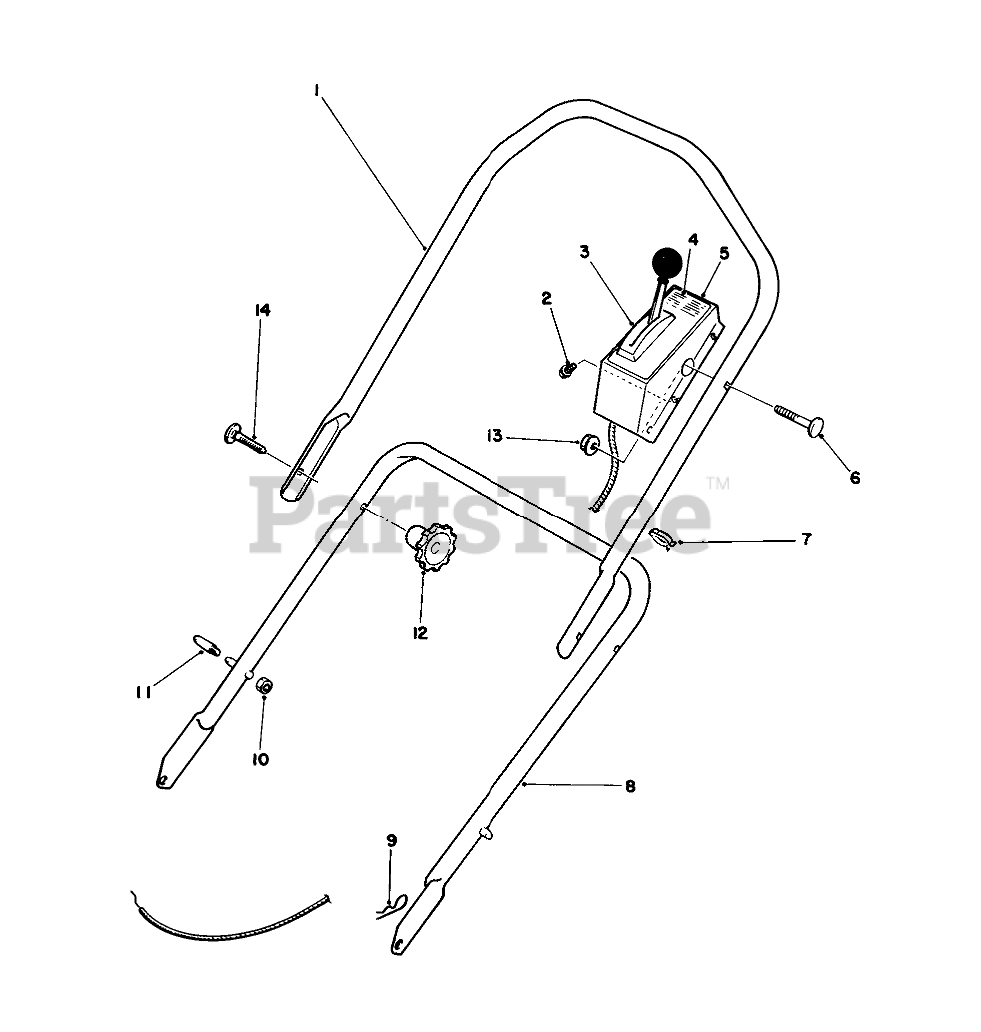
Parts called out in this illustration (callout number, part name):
1	Handle-Upper
2	SCREW-HWHTF
3	THROTTLE CONT-SERVICE
4	CONTROL COVER DECAL
5	Cover-Control (Incl. Ref. #4)
6	HANDLE SCREW
8	LOWER HANDLE ASM
9	PIN-COTTER, HAIR
10	NUT-LOCK, NI
11	HANDLE PIN
13	NUT-LOCK, HHF
14	5/16-18 X 2 HNDLE SCREW
